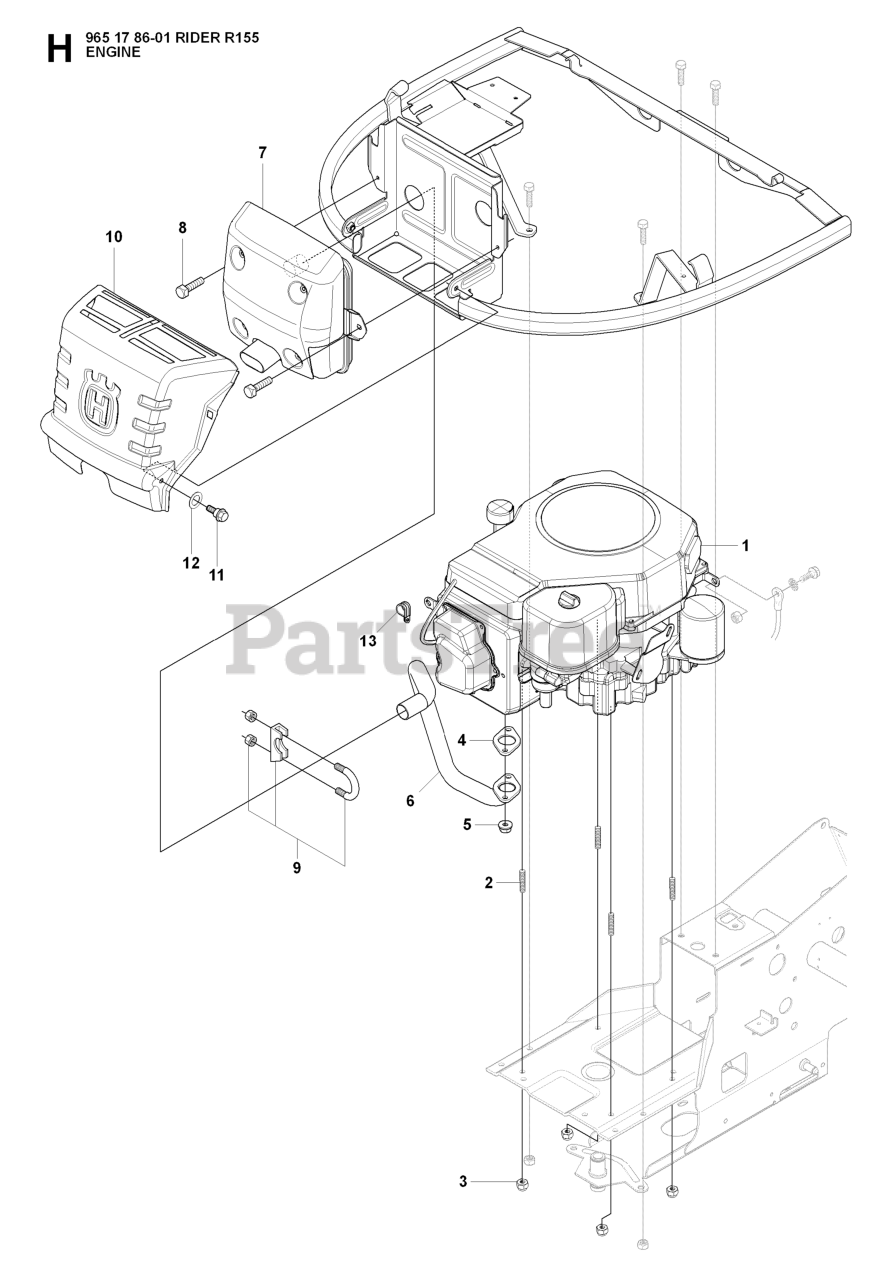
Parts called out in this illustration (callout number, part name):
3	LOCKNUT M8
4	EXHAUST GASKET
6	EXHAUST PIPE ASSY
7	MUFFLER ASSY
9	CLAMP
10	HEAT PROTECTOR
12	SPRINGWASHER
